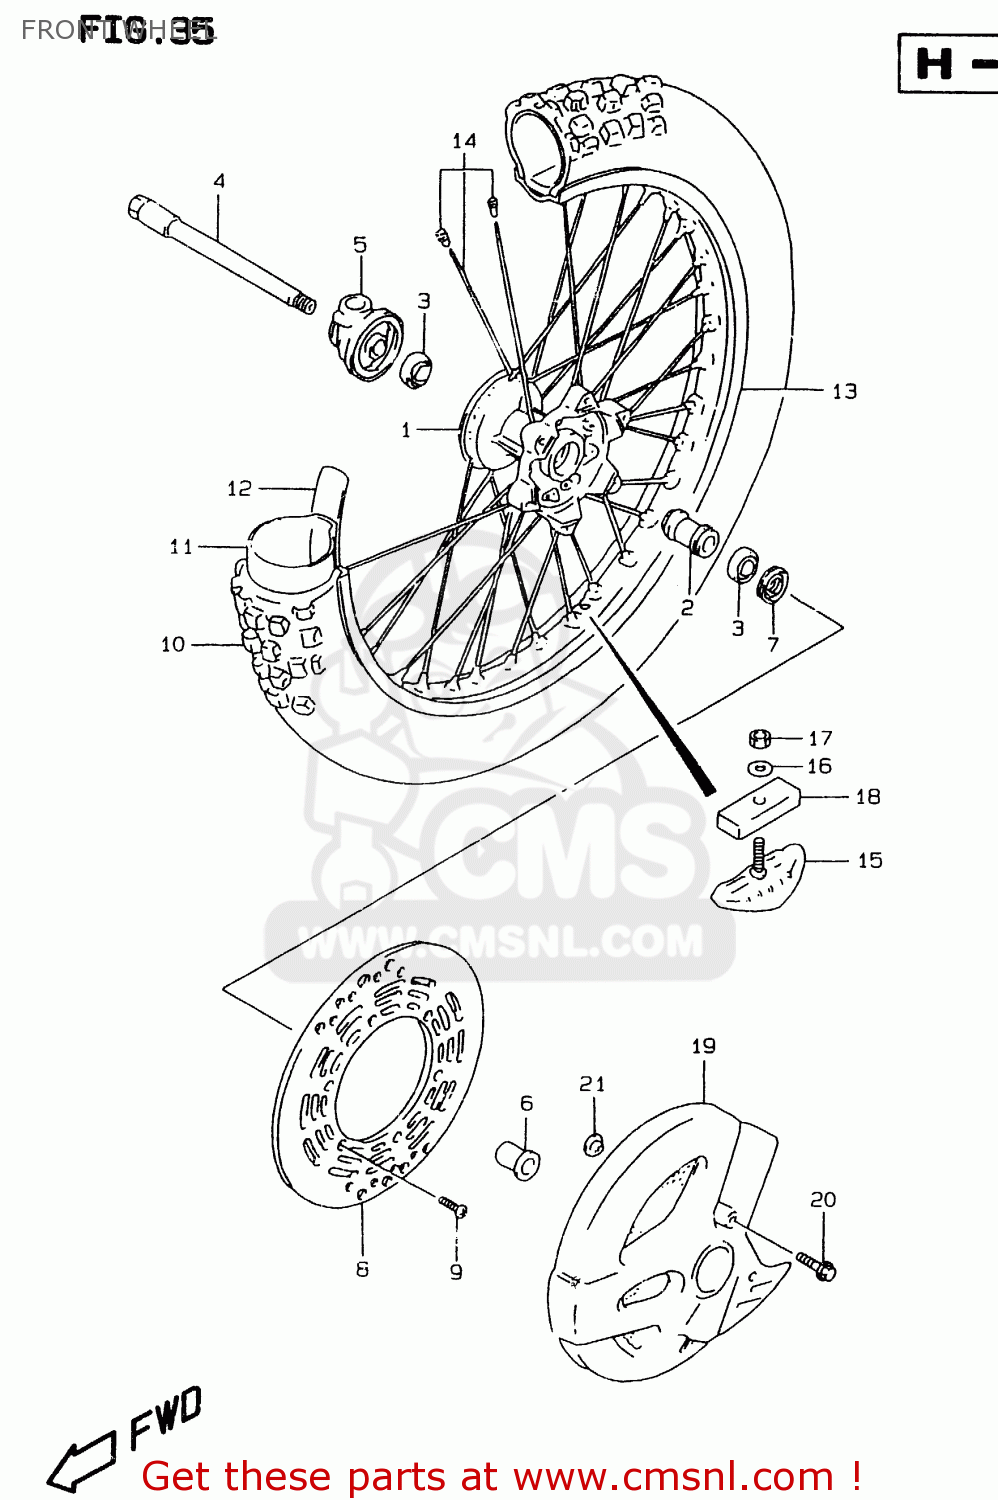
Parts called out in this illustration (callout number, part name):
1	HUB,FRONT WHEEL
2	SPACER,FR HUB BEARING
3	BEARING
4	AXLE,FR
5	BOX ASSY,SPEEDOMETER GEAR
6	SPACER,FR AXLE,L
7	SEAL,OIL(23X35X6)
8	DISC,FR BRAKE
9	SCREW
10	TIRE,FRONT 80/100-21
11	TUBE
12	PROTECTOR,WHEEL INNER
13	RIM,FRONT WHEEL (1.60X2
14	SPOKE SET,FR WHEEL
15	STOPPER,BEAD
16	WASHER
17	NUT
18	CUSHION,BEAD STOPPER
19	COVER,FRONT BRAKE DISC
20	BOLT(6X16)
21	WASHER
